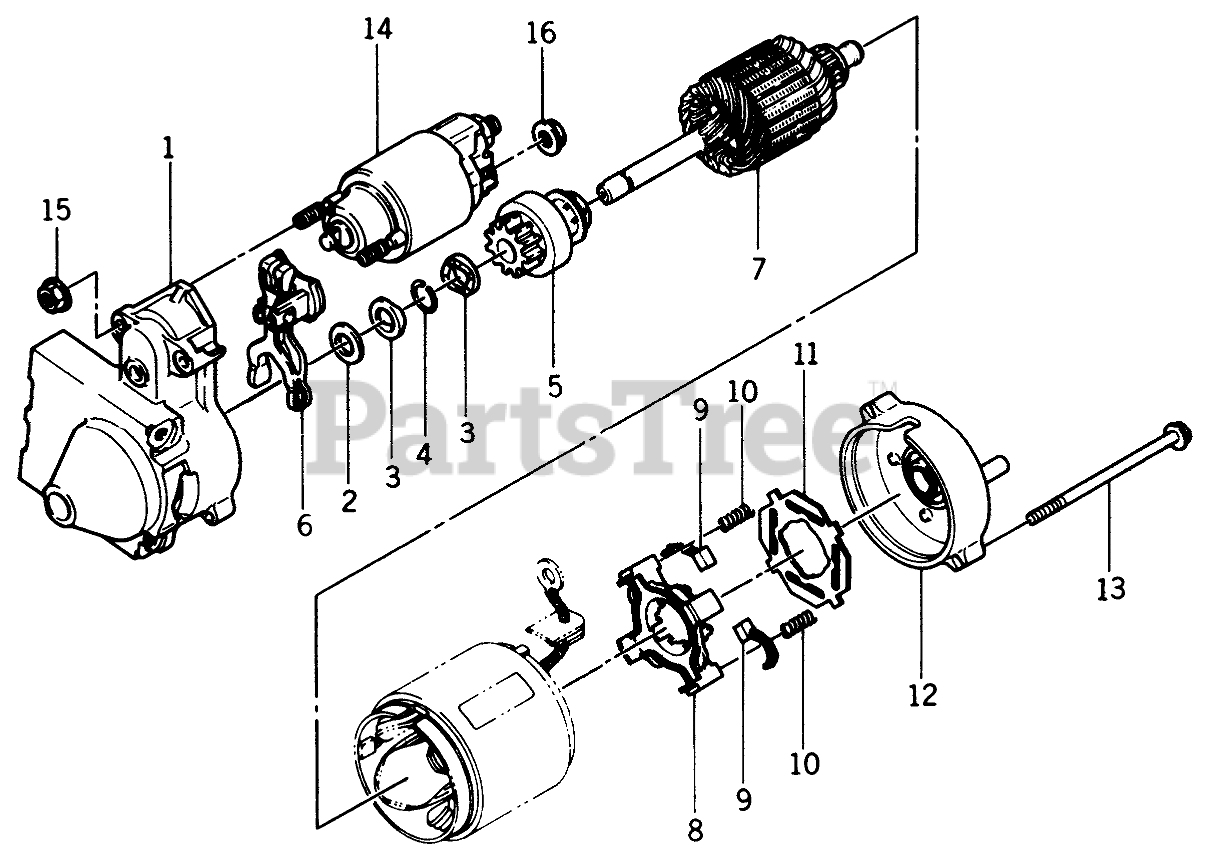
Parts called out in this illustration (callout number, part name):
1	Cover Assy
3	Stopper
5	Clutch Asm
6	Lever-Shift
8	Brush Holder
9	Brush
10	Spring-Brush
12	Cover Assy
13	Bolt
